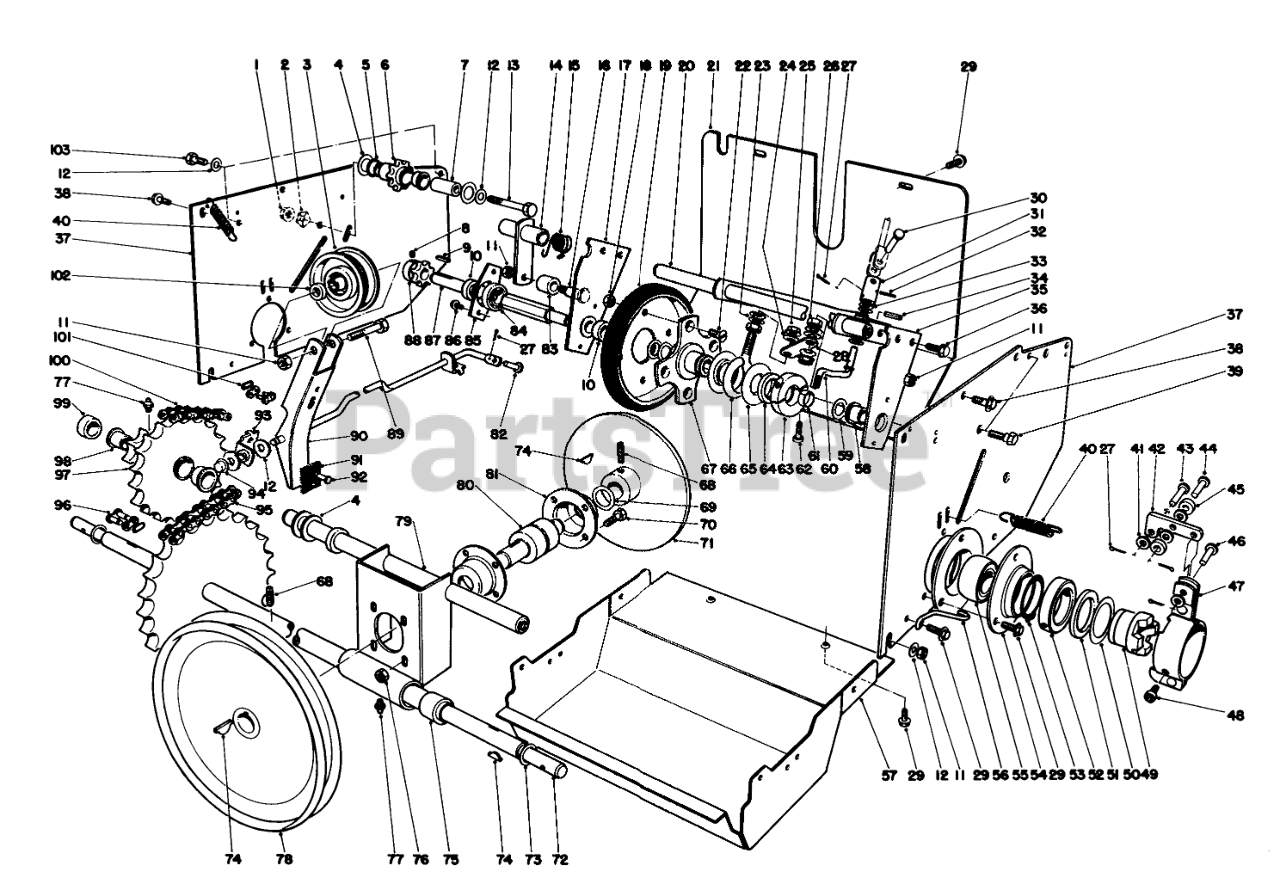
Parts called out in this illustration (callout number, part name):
1	NUT-HF
2	LOCKWASHER-PYRAMID
3	PULLEY-IDLER
4	WASHER-THRUST
5	BEARING-FLANGE
6	Sprocket Assembly (Incl. Ref. #5)
7	Standoff-Idler Sprocket
8	SCREW-HSH
10	SPACER
11	NUT-HEX
12	WASHER-FLAT
13	SCREW-HH
14	CHAIN TENSION ARM WA
15	TORSION SPRING
16	SHOULDER BOLT
17	HEX SHAFT MOUNT R
18	Nut
19	Disc
20	Bracket Dead Shaft
21	REAR COVER R
22	5/16-18X5/8 FLT HD MS
23	WASHER-FLAT
24	WASHER-SPRING
25	NUT-LOCK, FLANGE
26	Nut
27	PIN-COTTER
28	SHIFT ROD PIVOT
29	SCREW-HWH
30	CLEVIS PIN
31	U JOINT TUBE
32	PIN-SPRING
33	Clevis Pin
34	PIN-ROLL
35	Hex Shaft Mounting (Incl. Ref. #58)
36	SCREW-HWHTF
37	Cylinder Rest
38	SCREW-HHF
39	SHOULDER SCREW
40	EXTENSION SPRING
41	WASHER-FLAT
42	CLUTCH CAM ARM
43	PIN-CLEVIS
44	PIN-CLEVIS
45	CLUTCH ROLLER
46	PIN-CLEVIS
47	CLUTCH MT BRKT ASM
48	SCREW-HSH
49	WHEEL CLUTCH
50	THRUST WASHER
51	THRUST BEARING
52	CLUTCH MOUNT COLLAR
53	RING-RETAINING, EXTERNAL
54	BEARING FLANGE
55	BEARING
56	Clutch Retainer
57	LOWER SHIELD R
58	BUSHING
59	WASHER-FLAT
60	CONNECTION ROD
61	SPLIT SPACER
62	SCREW-HSH
63	ColIar
64	WASHER-THRUST
65	SLIDER RING
66	SLIDER RING COLLAR
67	TRACTION DISC HUB
68	Set Screw
69	Spacer
70	SCREW-HH
71	FRICTION PLATE O
72	AXLE SHAFT WA
73	WASHER
74	KEY-WOODRUFF
75	BUSHING
76	NUT-KEPS
77	FITTING-GREASE
78	Pulley
79	Bulkhead (Incl. Ref. #75)
80	BEARING-FRICTION PLATE
81	HOUSING BEARING
82	PIN-CLEVIS
83	CHAIN TENSION ROLLER
84	BEARING
85	BEARING CUP
86	SCREW
87	FRICTION WHEEL SHAFT
88	SPROCKET
89	SCREW-HH
90	Auger Brake (Incl. Ref. #91 & 92)
91	BRAKE PAD
92	.185 DIA X .375 RT +
93	Bracket-Clutch
94	PUSH NUT
95	ROLLER CHAIN
96	LINK-CHAIN
97	Sprocket (Incl. Ref. #98)
98	3/4ID X 3/4LG BSHG
99	SPACER-IDLER
100	1/4 X 42 CHAIN W/LINK
101	LINK-CONNECTING
102	Spacer
103	SCREW-HHFTF
